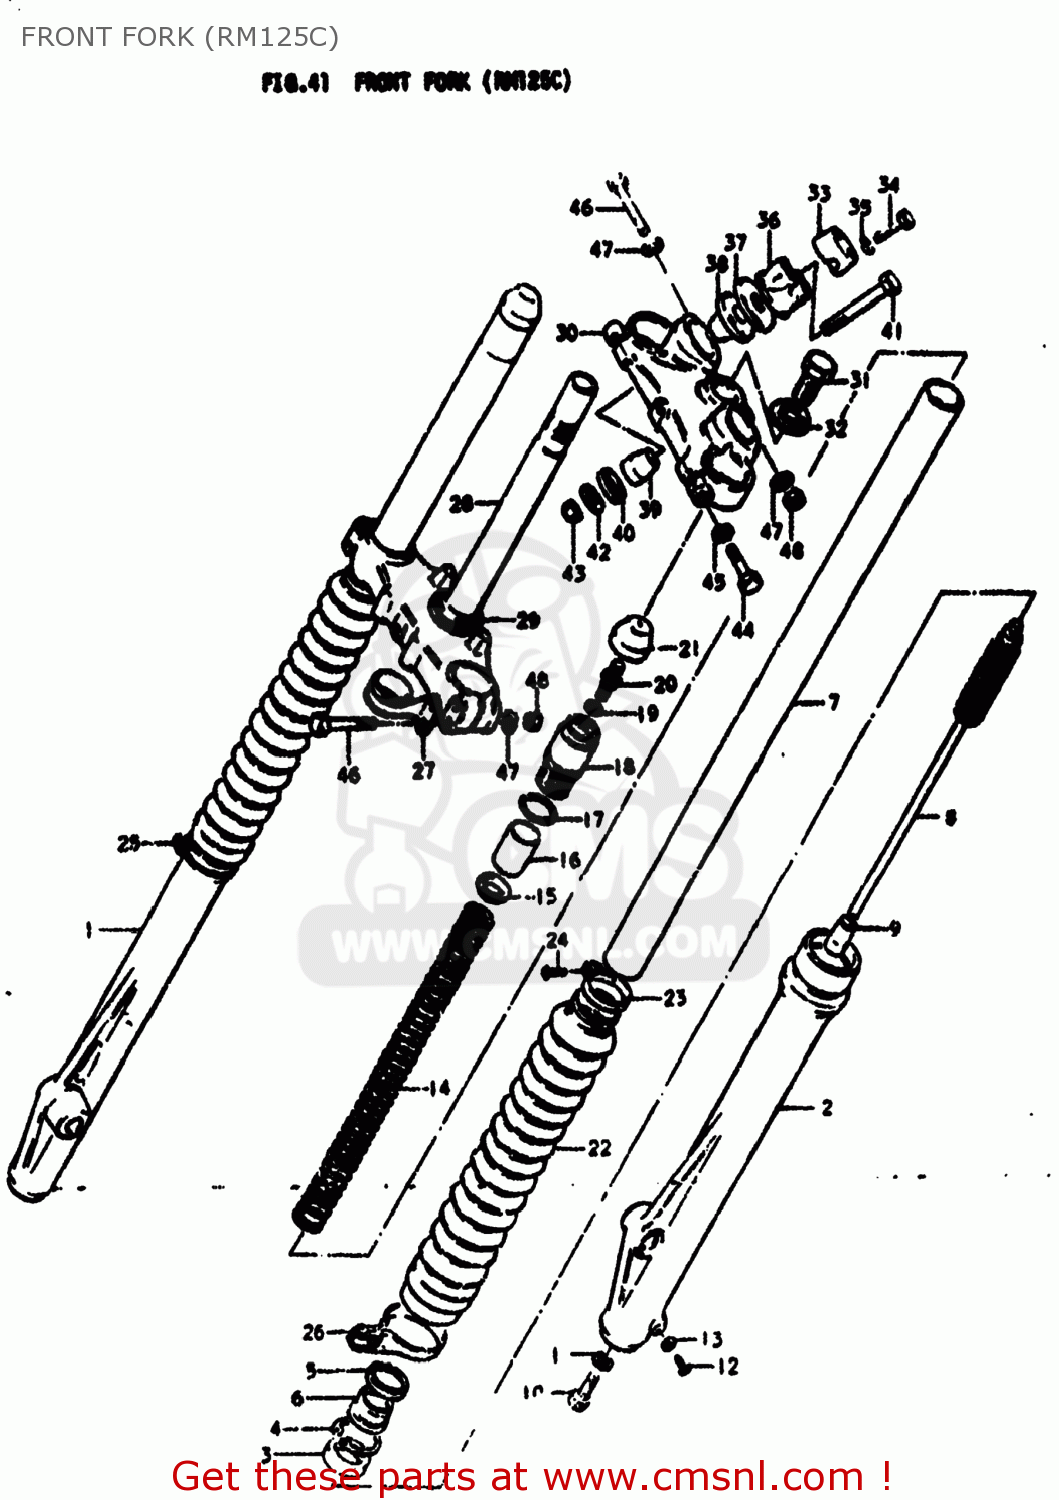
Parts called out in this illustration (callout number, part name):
1	TUBE,OUTER,RIGHT
2	TUBE,OUTER,LEFT
3	OIL SEAL,FRONT FORK
4	CIRCLIP,FORK OIL SEAL
5	GUIDE.FORK DUST
6	DUST SEAL,FRONT FORK
7	TUBE,FORK,INNER
8	CYLINDER,FRONT FORK
9	PIECE,OIL LOCK
10	BOLT,FORK CYLINDER(10X25)
11	GASKET (NAS)
12	SCREW
13	GASKET,DRAIN,PLUG (NAS)
14	SPRING
15	GUIDE,FRONT FORK SPRING C
16	SPACER,SPRING
17	O RING
18	CAP ASSEMBLY,FORK
19	O RING
20	VALVE
21	CAP
22	BOOT
23	BAND,BOOT
24	SCREW
25	BAND,FRONT FORK COVER
26	BAND,FRONT FORK COVER
27	GUIDE,CABLE
28	STEM,STEERING
29	RACE,STEERING OUTER LWR
30	HEAD,STEERING STEM
31	BOLT
32	WASHER
33	HOLDER,HANDLEBAR
34	BOLT
35	LOCK WASHER
36	HOLDER,HANDLEBAR
37	COVER, UPPER
38	CUSHION
39	RUBBER, LOWER
40	SPACER,STEERING DAMPER
41	BOLT,HANDLE HOLDER
42	WASHER
43	NUT 12MM
44	BOLT
45	LOCK WASHER
46	BOLT 8X55
47	WASHER
48	NUT
